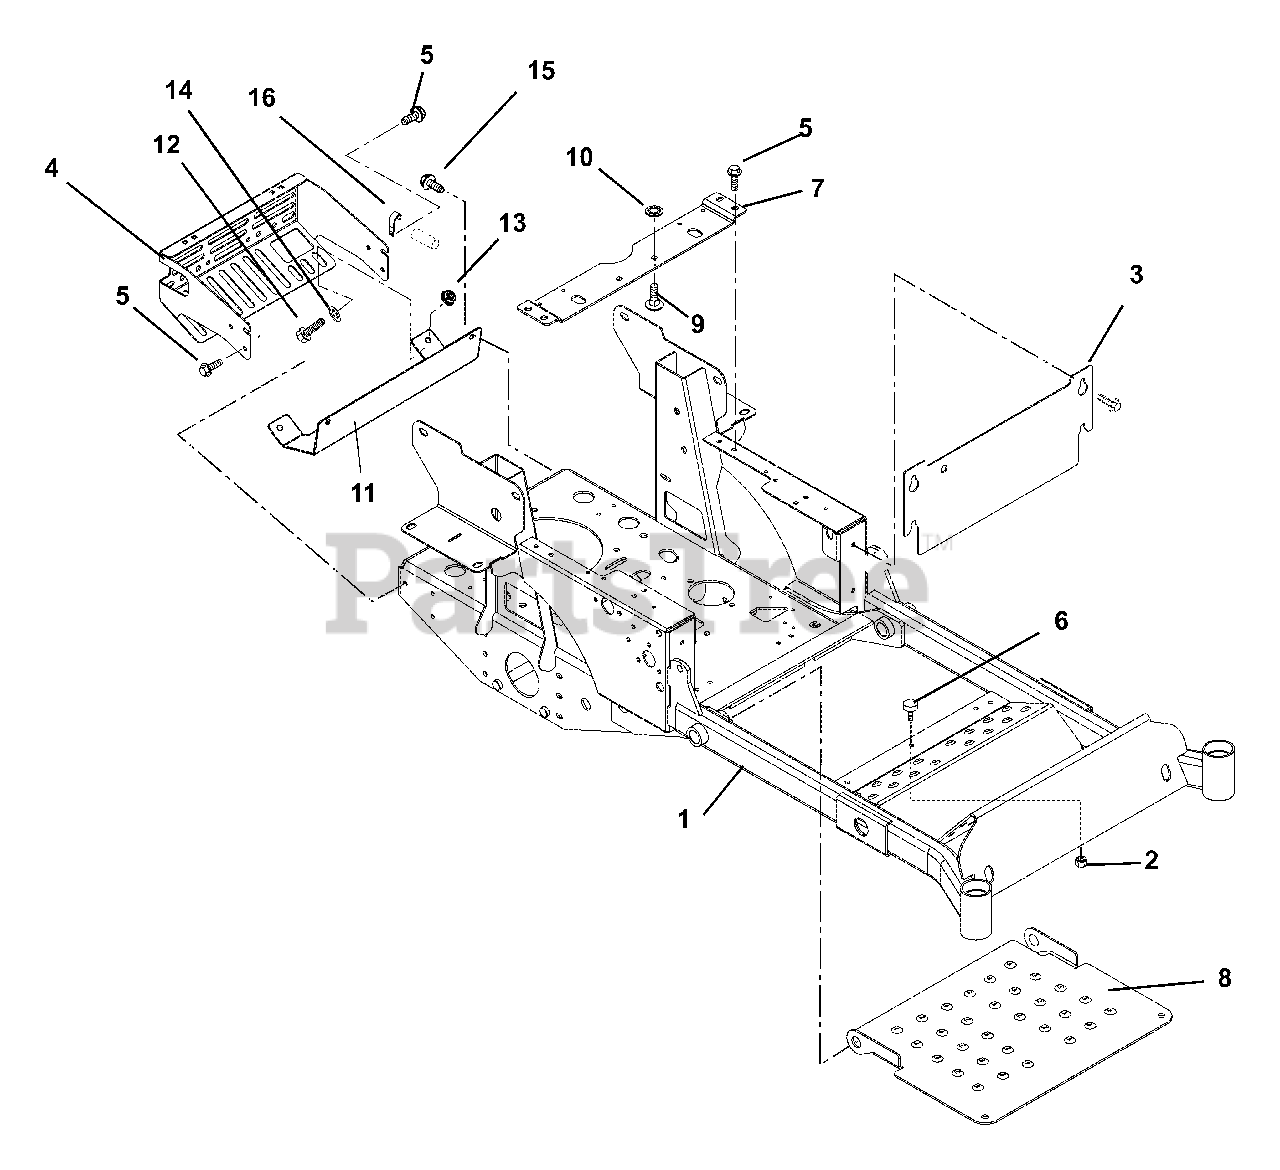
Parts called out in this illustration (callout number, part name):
1	WMT, FRAME COMPACT-Z
2	@NUT-SPNLK-FLG .312-18 YWZC
3	ACCESS PANEL - ORANGE
4	WMT, BUMPER W/ HEAT SHIELD CZC
5	@SCR-TAP .38-16X.75 HWH TR YWZ
6	BUMPER, RUBBER
7	SUPPORT, SEAT
8	PANEL, INSPECTION
9	@BLT-RHDSSQNK .31-18X.75 G5YZ
10	NUT-PUSH .312
11	SHIELD - HEAT - CZ PROD
12	@BLT-HEX .38-16X.75 GR5 YWZC
13	@NUT-LK-NYL-FLG .38-16 YWZC
14	@WSHR-FL-STL.438X1.00X.083 YWZ
15	@SCR-TAP .38-16X.50 HWH TR YWZ
16	J-CLAMP
